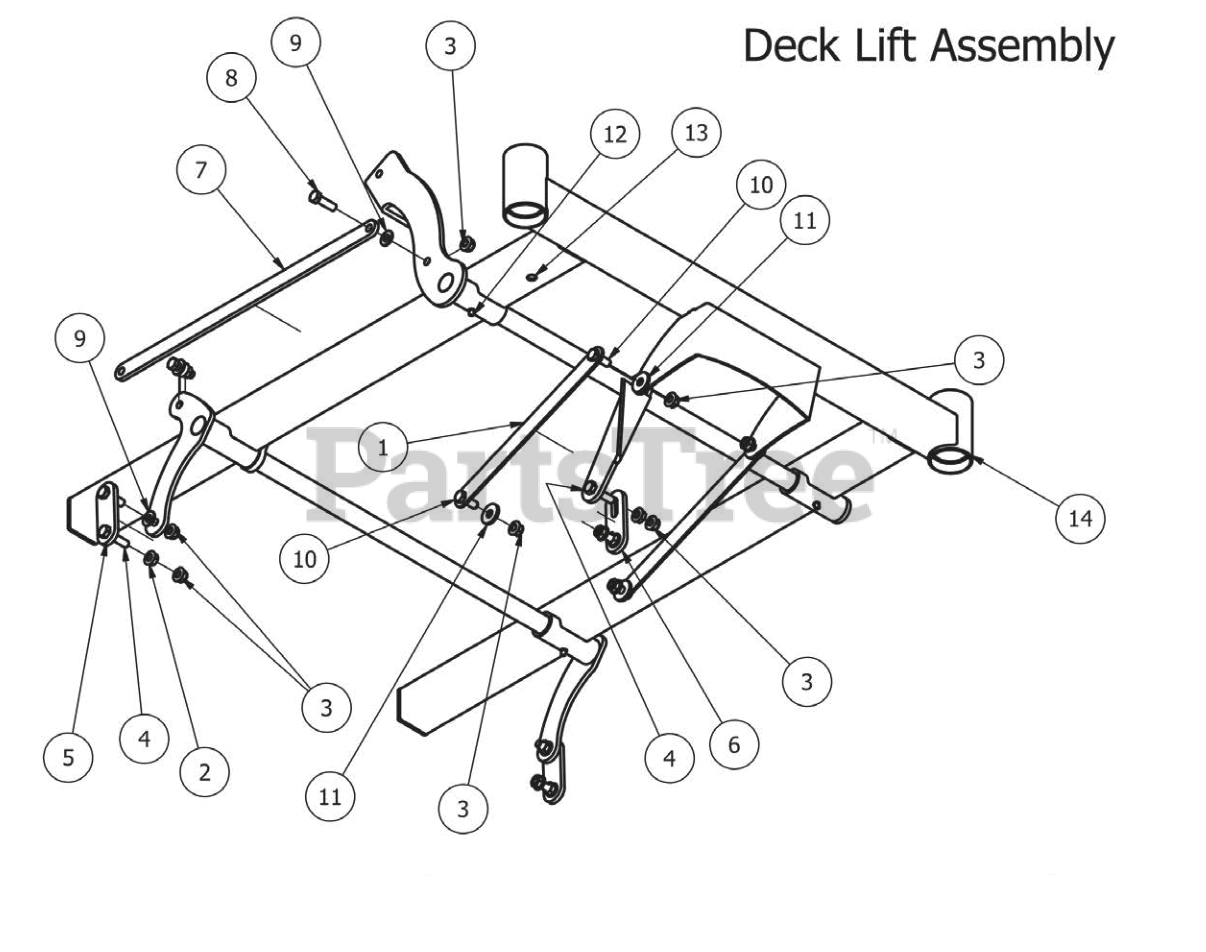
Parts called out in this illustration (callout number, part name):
1	MZ Front Arms
2	3/8" Flange Nut
3	3/8" Nylock Flange Nut
4	3/8" x 1 1/2" Hex Bolt
5	Deck Spacer (Rear)
6	Deck Spacer (Front)
7	Deck Linkage Rod
8	3/8" x 1 1/4" Hex Bolt
9	.360 ID Plastic Washer
10	3/8" x 1" Hex Bolt
11	.390 ID Plastic Washer
12	1/4" Drive in Grease Fitting
13	5/8 Round insert
14	Wheel bearing Container
